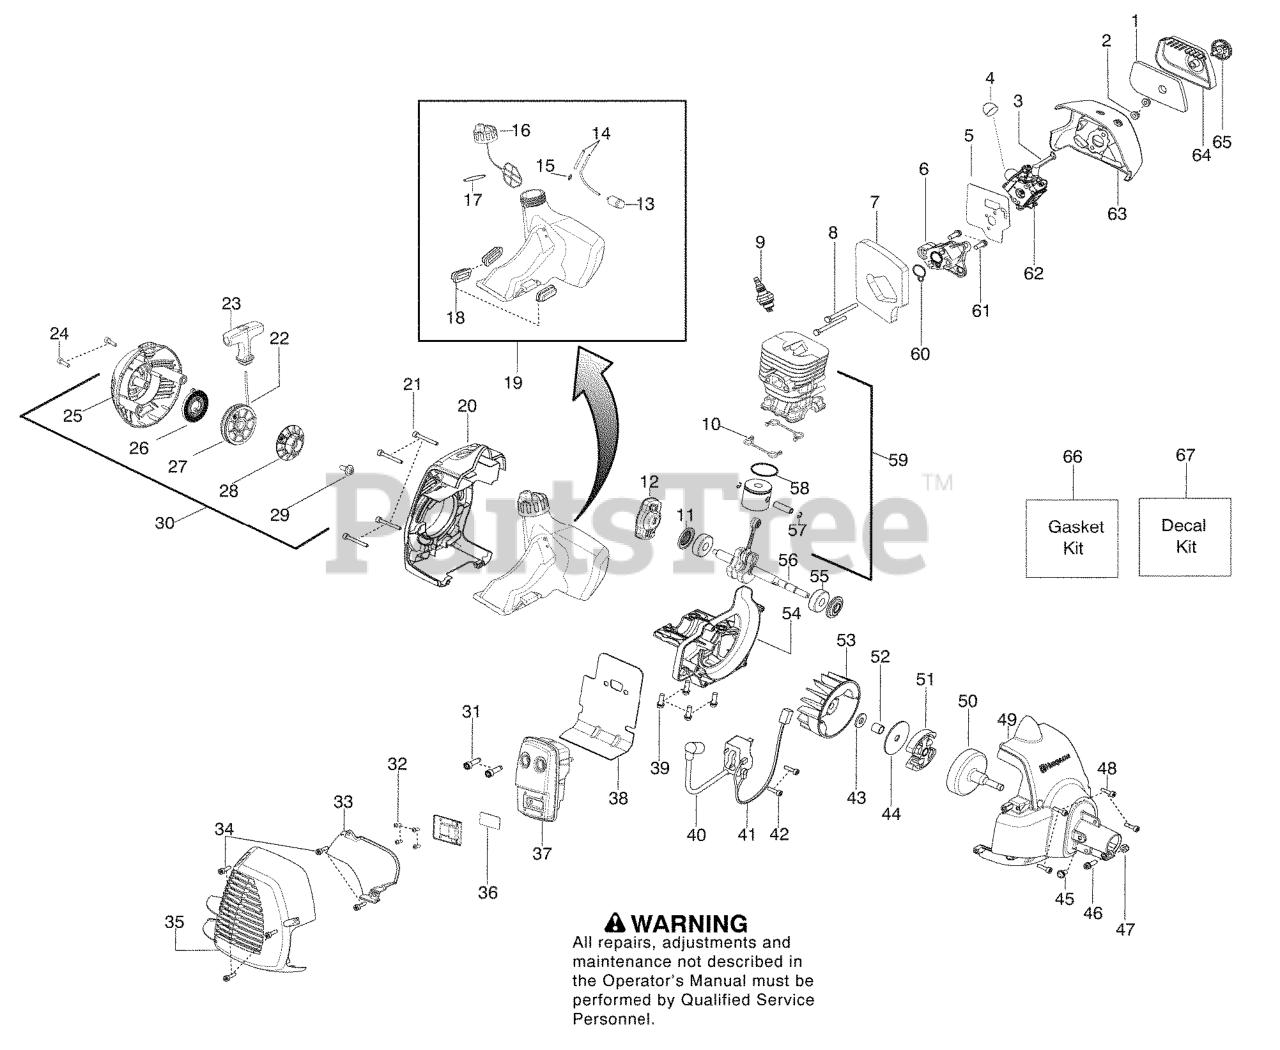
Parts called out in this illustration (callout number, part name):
2	Nut-Carb. Screw
3	Lever - Choke
4	Bulb-Purge
5	Kit-Carb. Gasket
6	Adaptor-Carb.
7	Foam-Gasket
9	Plug-Spark (RCJ-8Y)
10	Seal-Cylinder
11	Seal-Crankshaft
12	Assy-Starter Pawl
13	Assy-Fuel Filter
14	Kit-Fuel Line
15	Fitting-Fuel Line
16	Assy-Cap w/ret.
17	O-ring-Fuel Cap
18	Isolator-Fuel Tank
19	Kit-Fuel Tank Assy.
20	Shroud-Rear
22	Kit-Rope
23	Handle-Starter
25	Starter Hsg. w/eyelet
26	Kit-Starter Spring
27	Kit-Starter Pulley
28	Pulley-Driver
30	Assy-Starter Hsg.
31	Bolt-Muffler
32	Screw
33	Shield-Heat
35	Guard-Muffler
36	Kit-Spark Arrestor
37	Assy-Muffler
38	Gasket-Paper met.
41	Assy-Leadwire
44	Washer-Clutch
49	Assy-Fan Housing
50	Assy-Clutch Drum
51	Kit-Clutch Assy.
54	Crankcase
56	Assy-Crankshaft
57	Retainer-Piston Pin
58	Ring-Piston
59	Kit-Piston/Cyl.
60	Kit-Gasket
62	Kit-Carb.
63	Airbox
64	Cover-Air Box
66	Kit-Gasket
